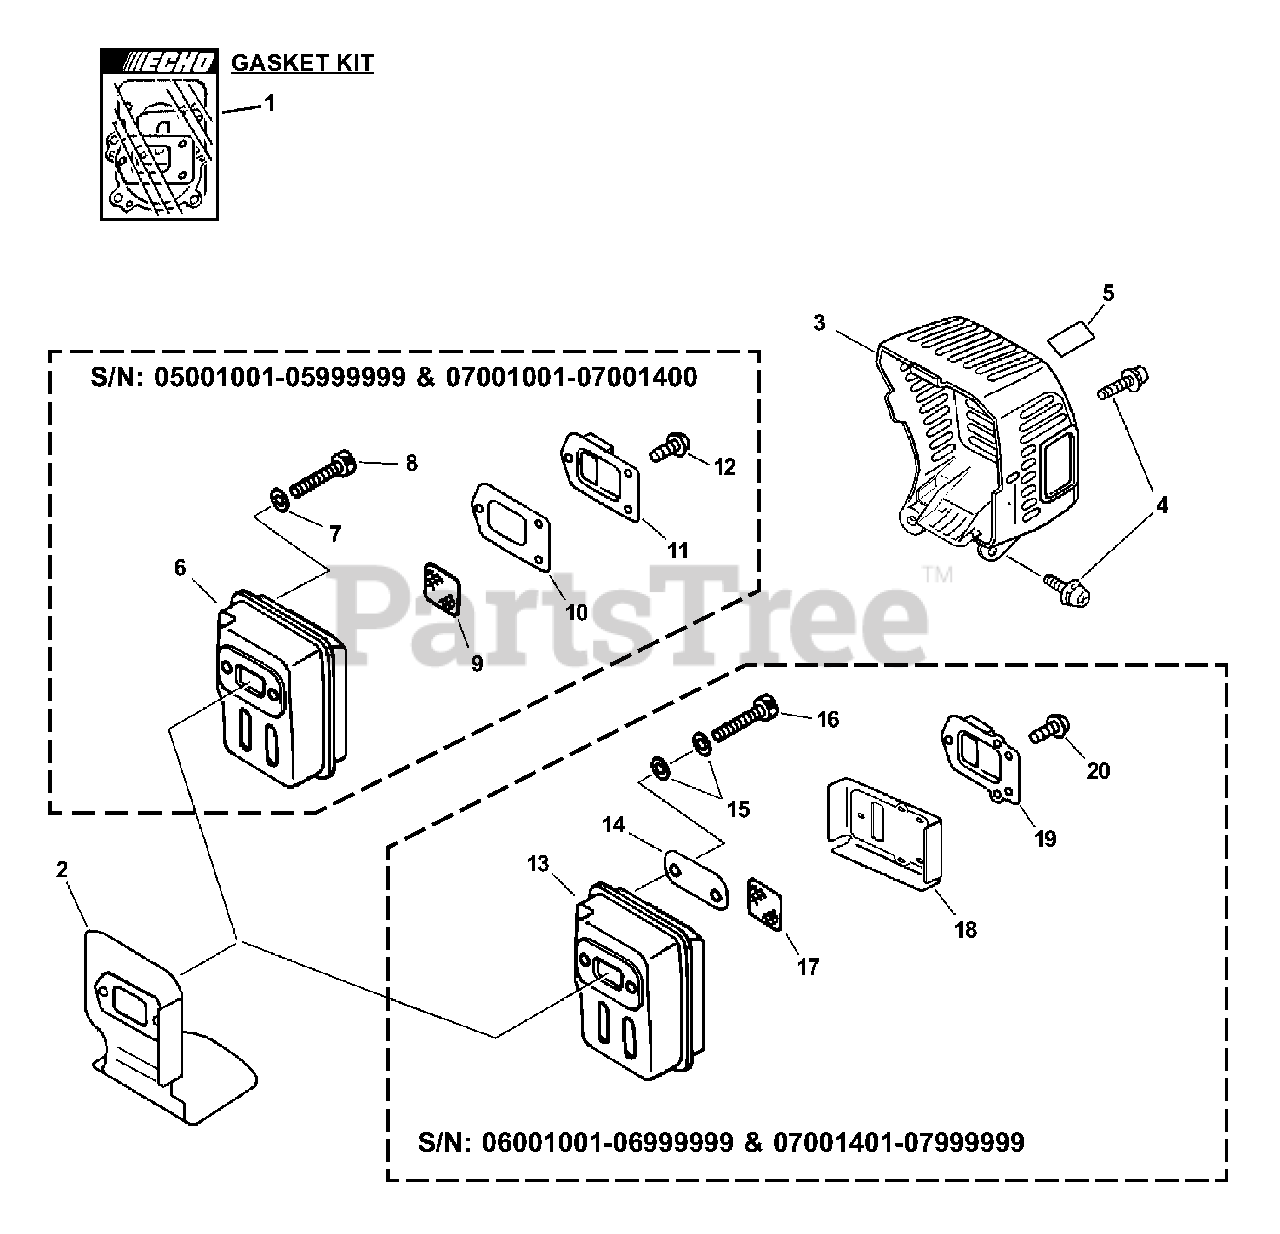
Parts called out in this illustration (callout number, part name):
1	GASKET KIT
2	HEAT SHIELD, EXHAUST
3	COVER, EXHAUST
4	BOLT 5×12
5	LABEL, CAUTION - HOT
7	WASHER, FLAT 5.5×10×0.8
8	BOLT 5×55
9	SCREEN, SPARK ARRESTER
10	GASKET, EXHAUST
11	GUIDE, EXHAUST
12	SCREW 4×10
13	MUFFLER
14	PLATE, EYE
15	CONICAL WASHER
16	BOLT 5×55
17	SCREEN, SPARK ARRESTER
18	GASKET, EXHAUST
19	GUIDE, EXHAUST
20	SCREW 4×10
